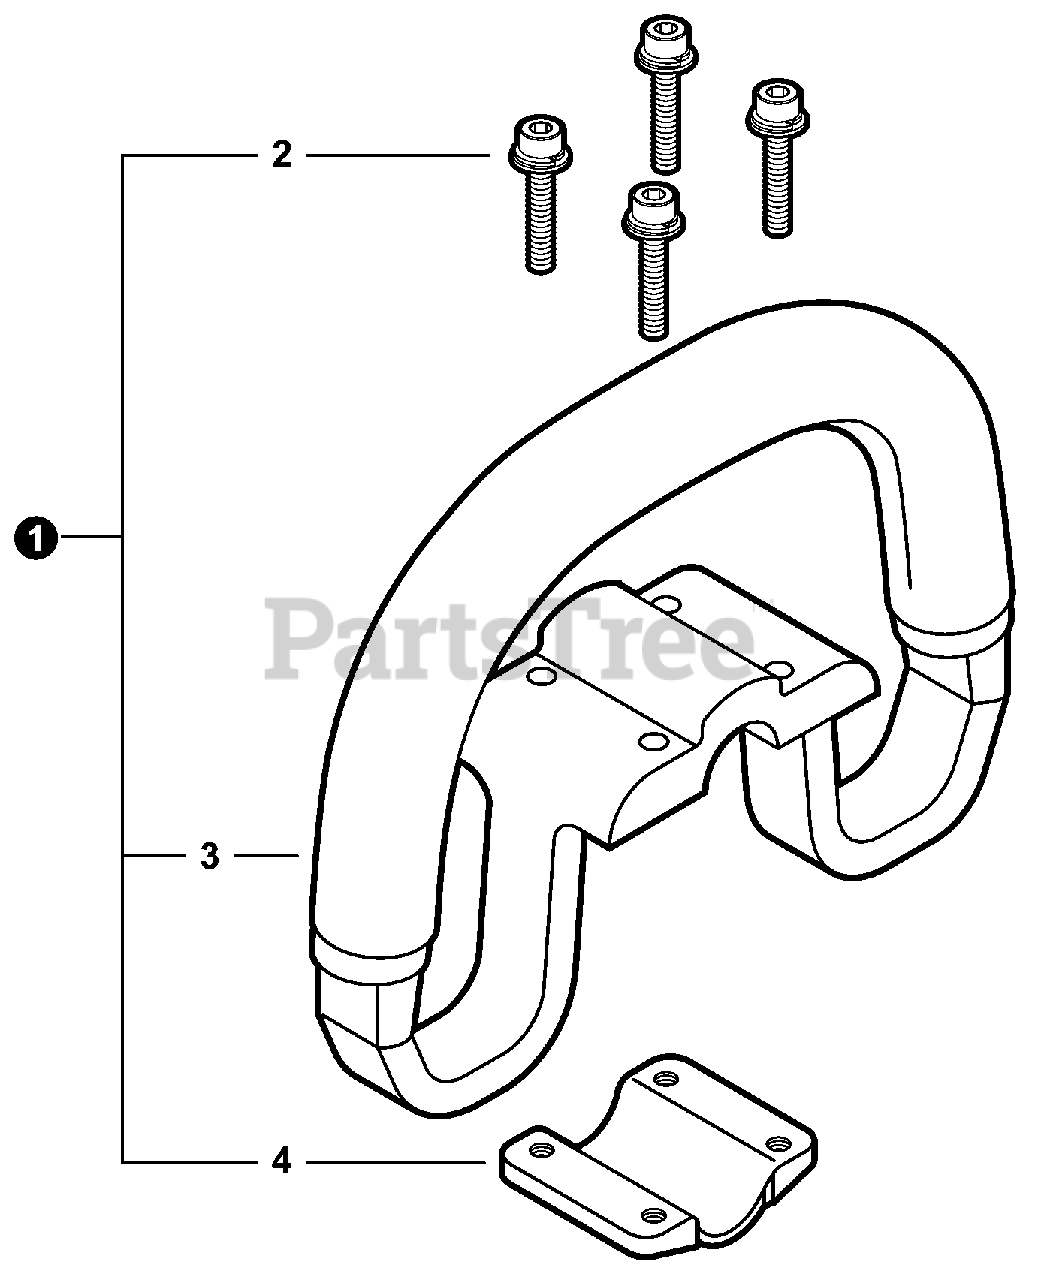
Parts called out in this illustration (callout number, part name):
1	HANDLE ASSY - SUPPORT
2	BOLT M5×25
4	BRACKET, MOUNTING
